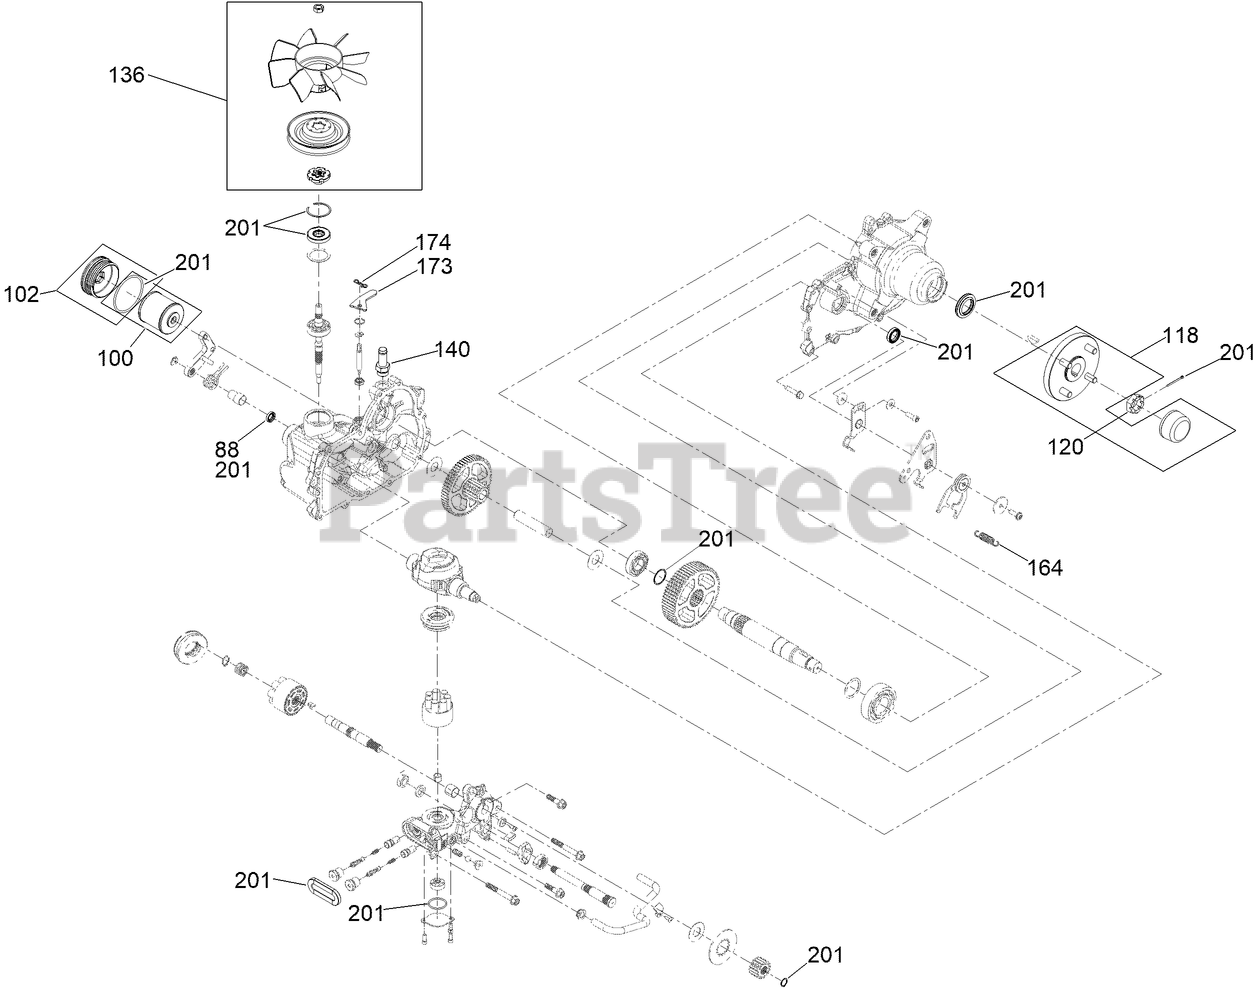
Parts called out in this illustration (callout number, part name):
88	SEAL, BRAKE
100	KIT, FILTER
102	KIT, FILLER CAP
118	HUB-4 BOLT
120	NUT, SLOTTED
136	KIT, FAN AND PULLEY
140	FITTING-5/8 BEADED, 7/8 SAE
164	SPRING-EXTENSION
173	PLATE-LEVER, BYPASS
174	PIN-COTTER, LOCKING
201	KIT, SEAL
